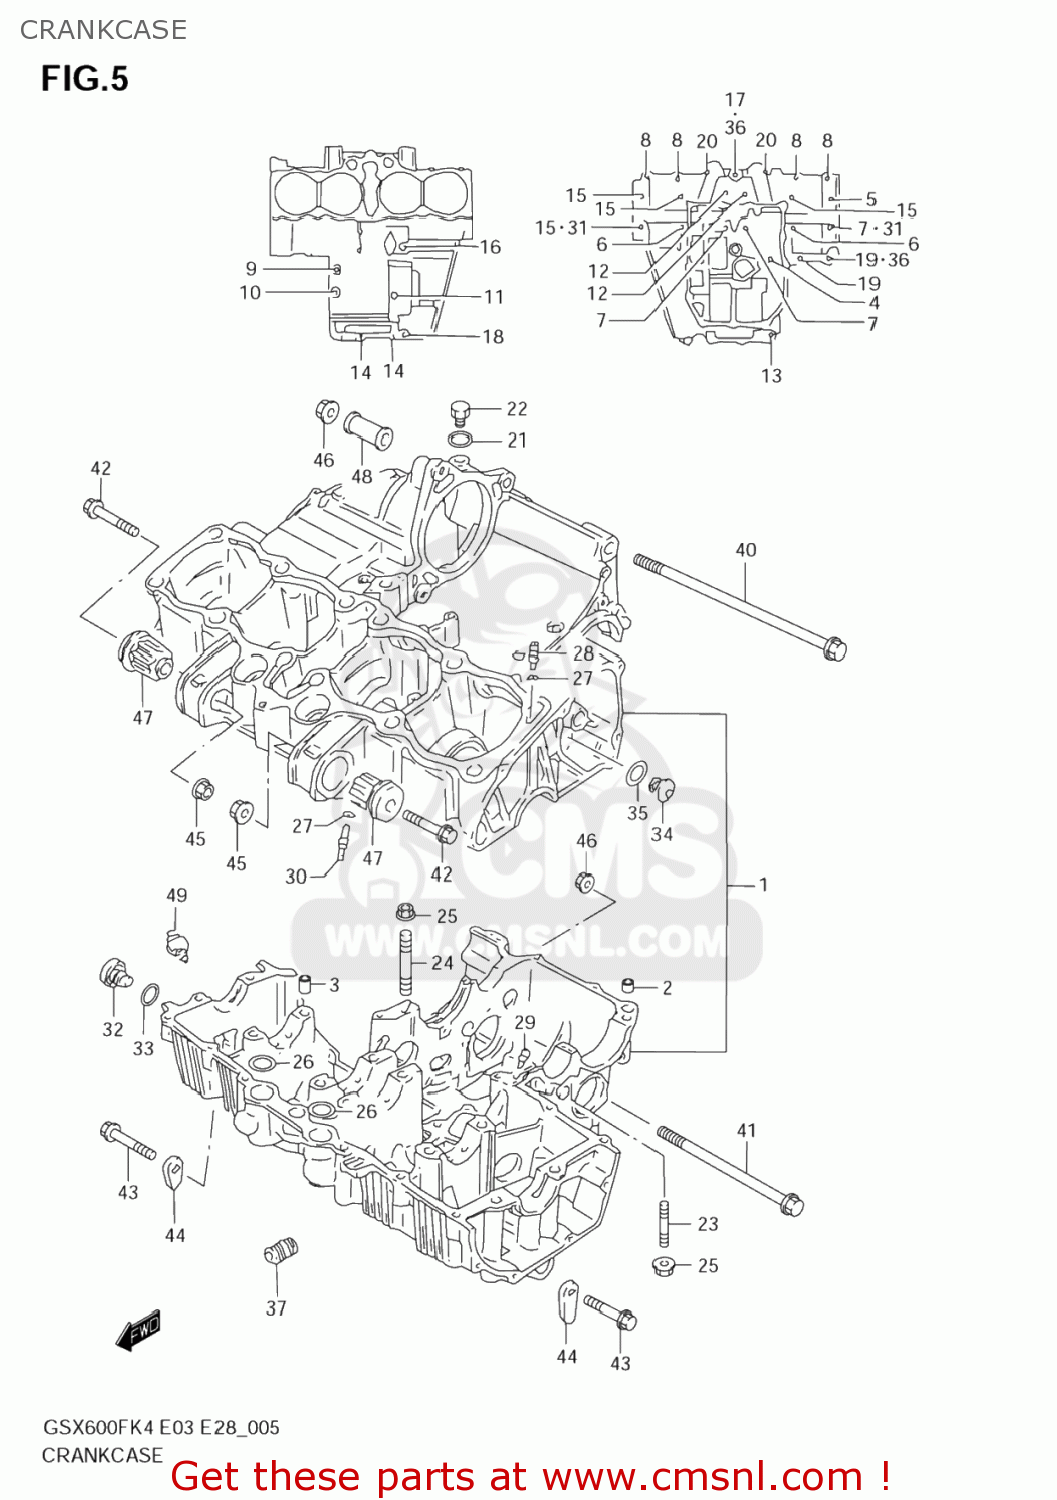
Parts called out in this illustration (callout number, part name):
1	CRANKCASE SET
2	PIN(10.4X13X22)
3	PIN(8.4X11X20)
4	BOLT(6X105)
5	BOLT(8X105)
6	BOLT(8X125)
7	BOLT(8X115)
8	BOLT
9	BOLT
10	BOLT,CL.COVER
11	BOLT
12	BOLT
13	BOLT
14	BOLT
15	BOLT(8X95)
16	BOLT
17	BOLT
18	BOLT
19	BOLT, HYDRAULIC UNIT NO.2
20	BOLT
21	GASKET(12.1X16.2X3.7) (NAS)
22	PLUG(12X9)
23	STUD BOLT
24	STUD BOLT
25	NUT
26	O RING(D:2.5,ID:21)
27	O RING(D:1.2,ID:4)
28	JET,AIR
29	JET
30	JET(13)
31	GASKET(8.5X17X2.3) (NAS)
32	PLUG
33	O RING(D:2.4,ID:16.8)
34	PLUG
35	GASKET(13.8X18.8X4.8) (NAS)
36	GASKET(5.8X13X1.2) (NAS)
37	UNION,OIL STAND
38	PLATE,CRANK THRUST
39	PLATE,CRANK THRUST
40	BOLT(10X175)
41	BOLT(10X130)
42	BOLT
43	BOLT(10X50)
44	NUT
45	NUT
46	NUT
47	BUSH,ENGINE MOUNTING
48	SPACER,ENGINE MOUNT(L27)
49	SWITCH ASSY,OIL PRESSURE
